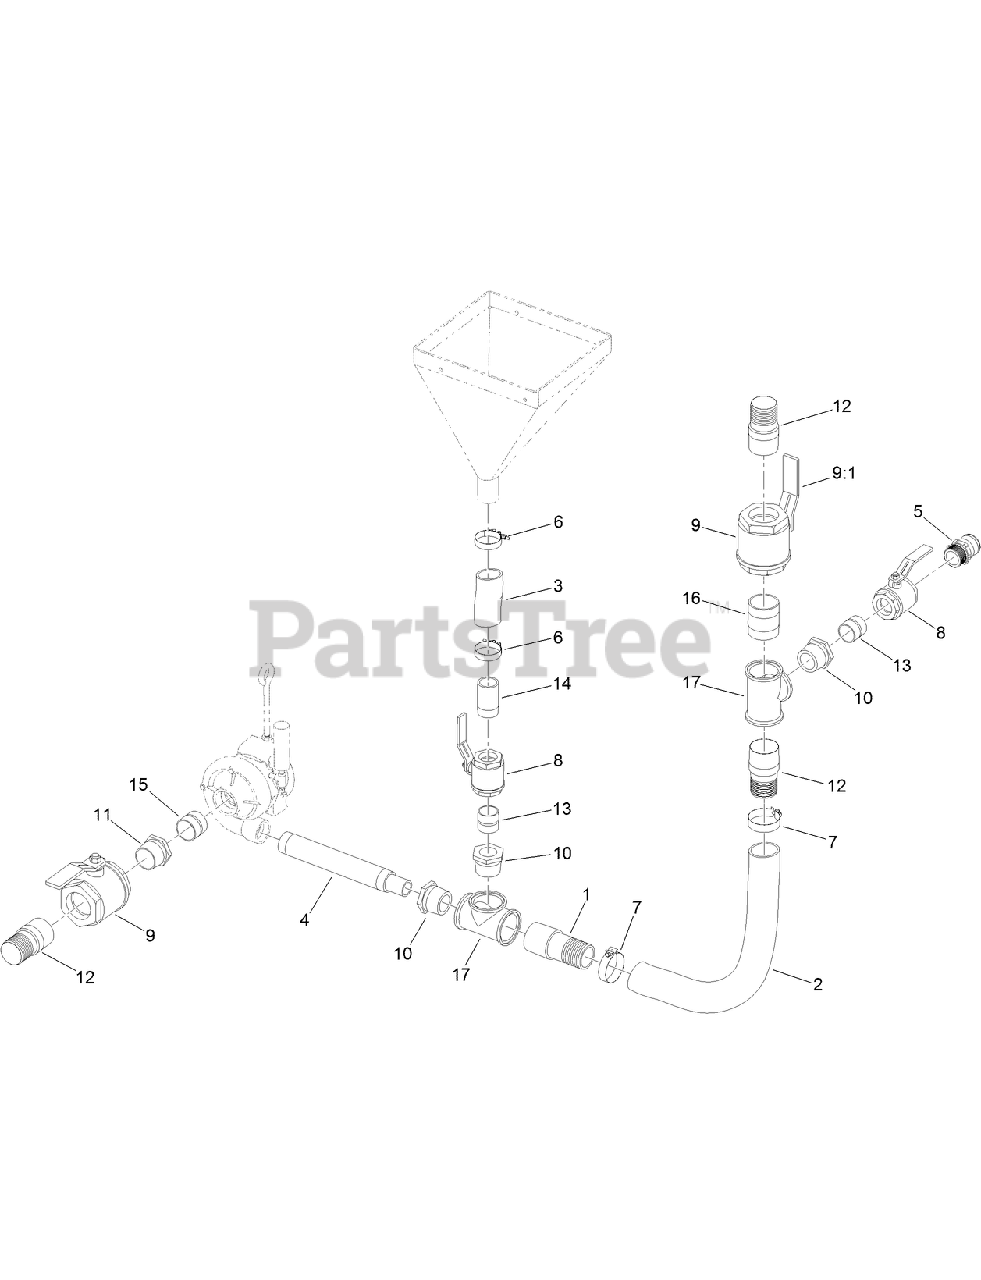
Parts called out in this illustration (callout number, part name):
1	TUBE-VENTURI
2	HOSE-SUCTION, WATER
3	HOSE-SUCTION, WATER
4	TUBE-JET
5	ADAPTER-MALE
6	CLAMP, T-BOLT
7	CLAMP-T BOLT
8	VALVE-BALL (2.0)
9	VALVE-BALL (3.0)
9:1	HANDLE-BALL, 3.0 VALVE
10	BUSHING-PIPE
11	BUSHING-PIPE
12	NIPPLE-COMBINATION
13	NIPPLE-PIPE
14	NIPPLE-PIPE
15	NIPPLE-PIPE
16	NIPPLE-PIPE
17	TEE-PIPE
